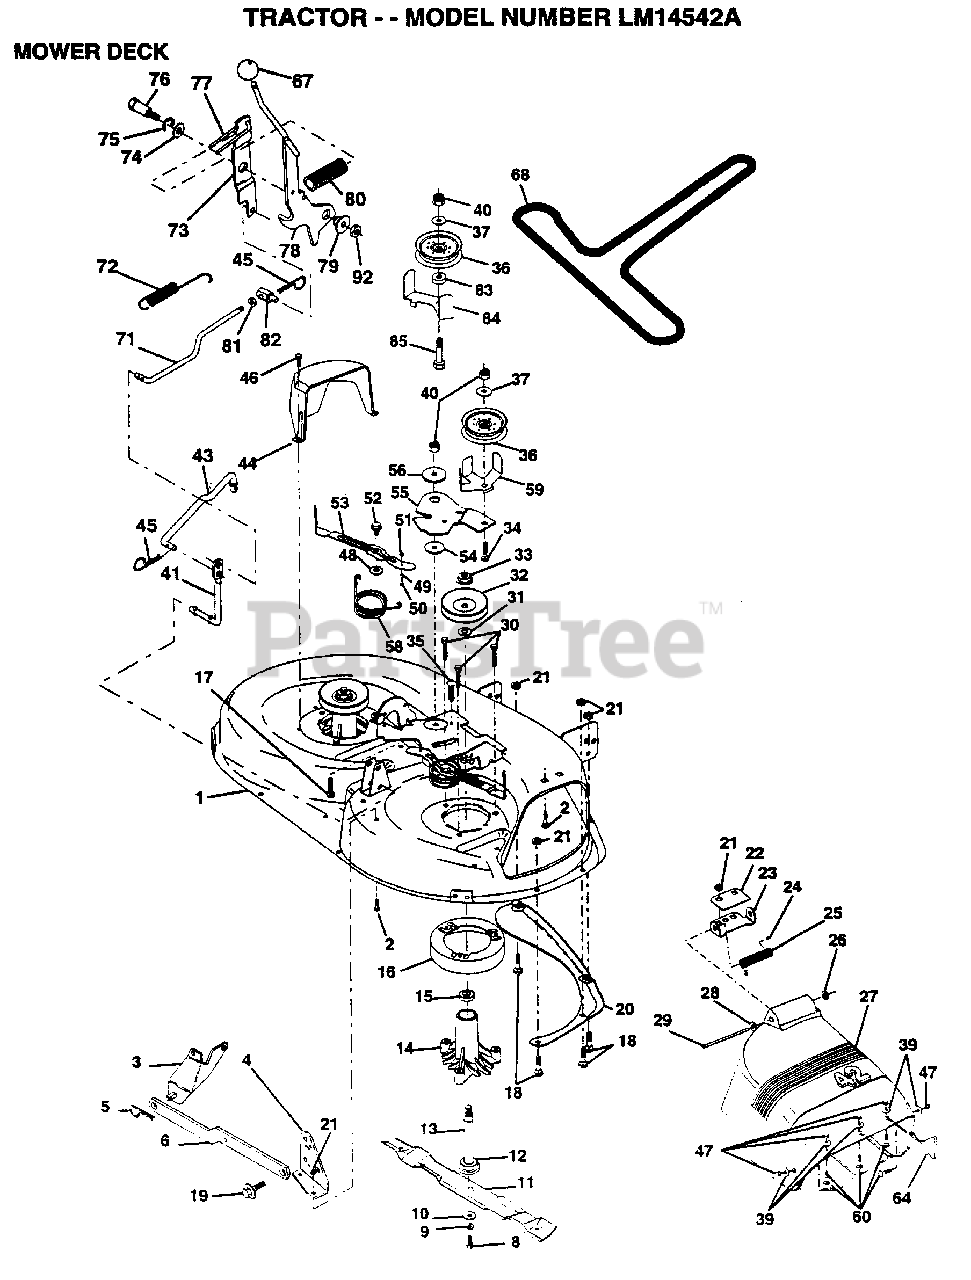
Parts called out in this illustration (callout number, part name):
1	DECK.WELD.42.
2	BOLT
3	BRKT ASM SWAY BAR
4	BRKT DECK SW BAR
8	BLADE BOLT
10	WASHER.HARD.BLADE
11	"BLADE.42"" HIPERF"
12	BEARING.BALL
14	HSG ASM MANDREL
15	BEARING
16	STRIPPER RND MWR
17	BOLT RDHD 3/8-16
18	BOLT
19	BOLT SHD 5/16-18
22	STIFFENER BRKT
23	DEFLECTOR BRKT
24	CAP-SLEEVE LT
25	SPRING TORSION
26	NUT PUSH M
27	DEFLECTOR.CLIP.TU
28	WASHER
29	HINGE ROD
31	WASHER
34	BOLT
35	XMAS TREE FASTNER
36	FLAT IDLER PULLEY
37	WASHER
41	PIVOT ROD
43	ROD CLUTCH W/NIBS
44	GUARD MAND LH BLK
45	RETAINER M
46	SCREW.1/4-20X5/8
48	HARD SMALL WASHER
50	SHOULDER BOLT
51	LOCKNUT
52	BOLT.SHLD.5/16-18
53	BRAKE PAD ARM ASM
54	HARDENED WASHER
56	SPACER RETAINER
58	SPRING TORSN BRAK
59	GUARD IDLER TUV
60	BOLT M5X0.8X16
64	GUARD.FOOTREST.42
67	KNOB T(3/8 HOLE)
68	BELT.V.T-PATH
71	ROD CLUTCH 38/42
72	RETURN SPRING
73	CLUTCH ARM SECOND
74	WASHER
75	RING
76	SHOULDER BOLT
77	SPRING KEEPER
79	BUSHING
81	NUT
82	TRUNION ADJ
83	WASHER
85	BOLT RDHD 3/8-16
92	NUT
